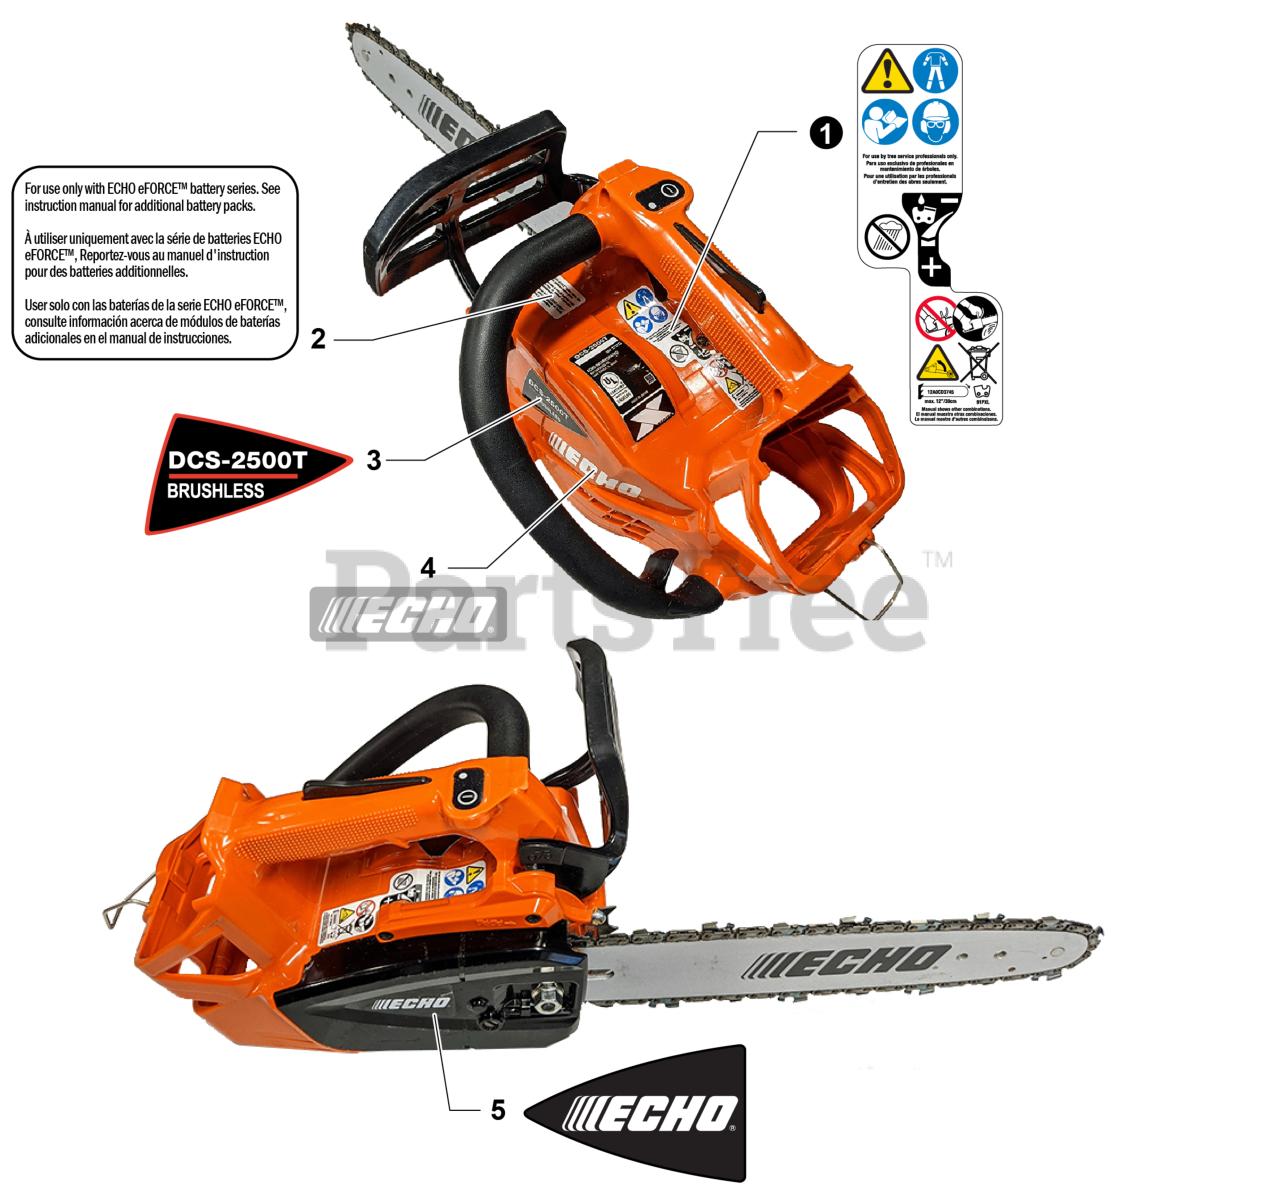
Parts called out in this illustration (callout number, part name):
1	LABEL - CAUTION - UL
2	LABEL - CAUTION - BATTERY
3	LABEL - MODEL - DCS-2500T
4	LABEL - ECHO
5	LABEL - ECHO
